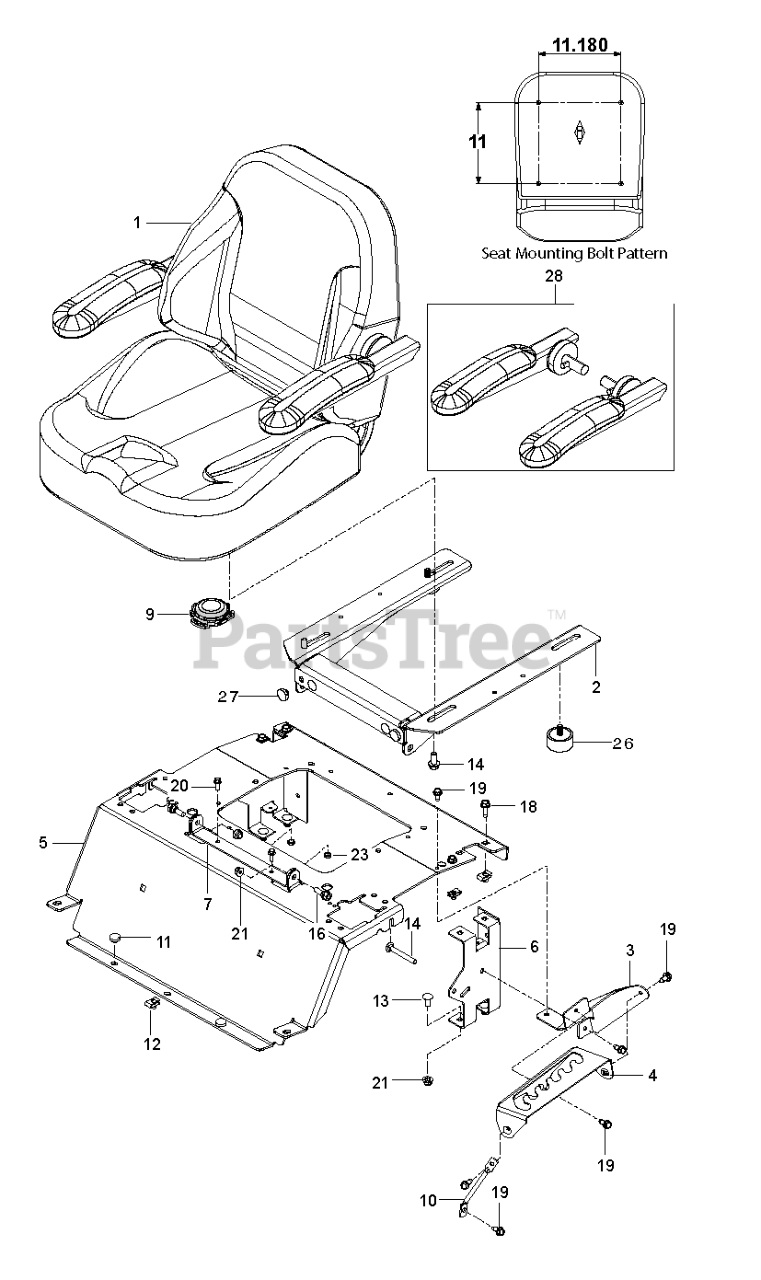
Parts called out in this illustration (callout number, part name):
3	PLATE.SUPPORT.DECK.LIFT.X431
4	PLATE.DECK.LIFT.X431
5	PLATE SEAT SUPPORT; RZ ORANGE
6	SUPPORT REAR SEAT BLACK
7	BRACKET.SEAT.REINF.X672
9	SWITCH.SEAT.DELTA.OPC.
10	SUPPORT.LEG.DECK.LIFT
11	GROMMET.BUMPER
12	U-CLIP 5/16-18 NUT RETAINER
13	BOLT 5/16C X 3/4" CARRIAGE
16	BOLT SHOULDER 5/16-18 UNC
18	SCREW.THDROL.5/16-18X3/4.TTY
19	BOLT.5/16HEX.WHS.HD
20	SCREW.FLG.LOCKING.1/4-20X.75
21	5/16-18 NYLOC FLANGE NUT
23	NUT
26	BUMPER 5/16-18 CLEAR ZINC
27	GROMMET, BUMPER
28	SEAT KING 18" WOOD BTM, ARM
